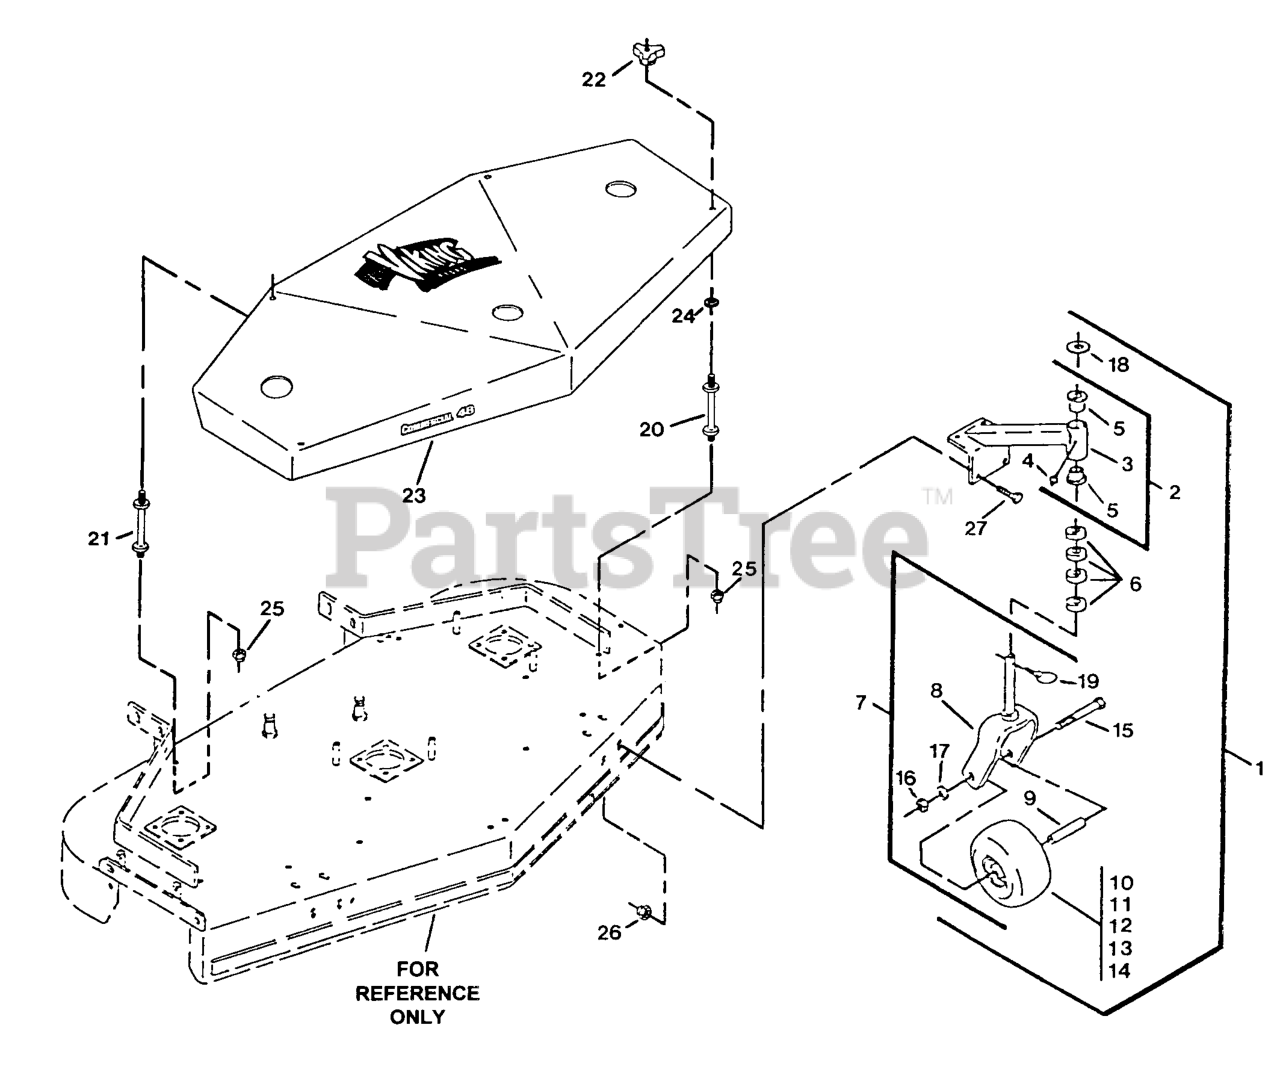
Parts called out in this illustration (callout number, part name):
1	CASTER/MOUNT ASM
2	SUPPORT ASM
5	BEARING-FLANGED
6	SPACER-CASTER
13	BEARING
14	BUSHING
18	WASHER-FLAT
20	STUD-SHIELD, BELT (SHORT)
21	STUD-SHIELD, BELT (LONG)
22	KNOB-3 PRONG
